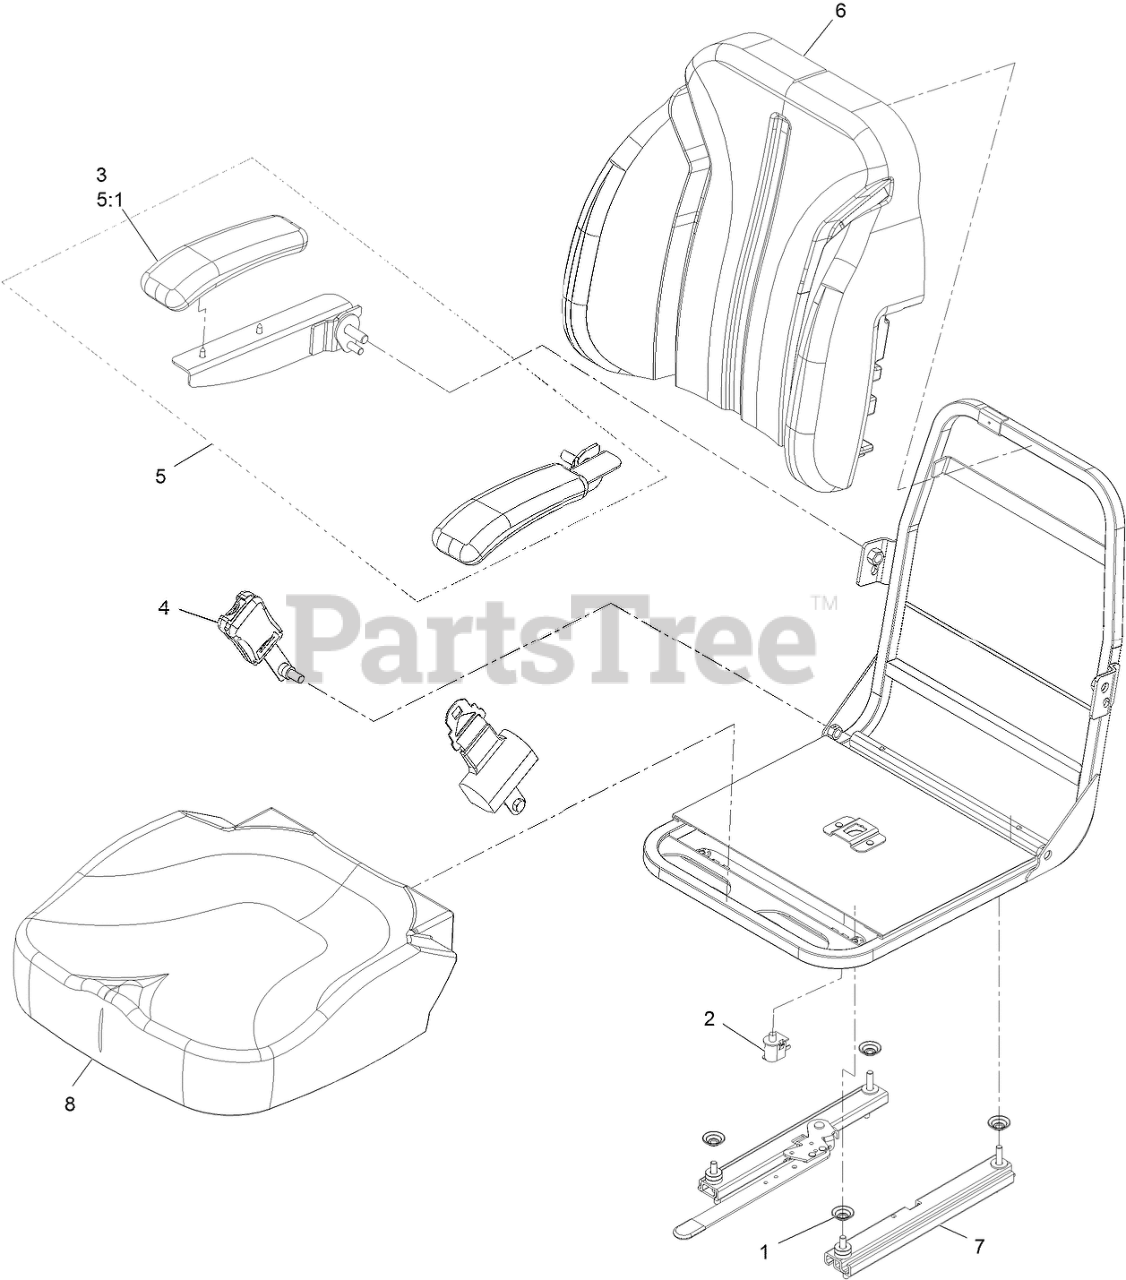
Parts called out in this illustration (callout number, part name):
1	SPACER-MOUNTING
2	SWITCH-BAIL
3	CUSHION-REST, ARM
4	SEAT BELT KIT
5	ARMREST KIT
5:1	CUSHION-REST, ARM
6	COVER-SEAT BACK SVC
7	TRACK-SEAT
8	COVER-SEAT BOTTOM SVC
